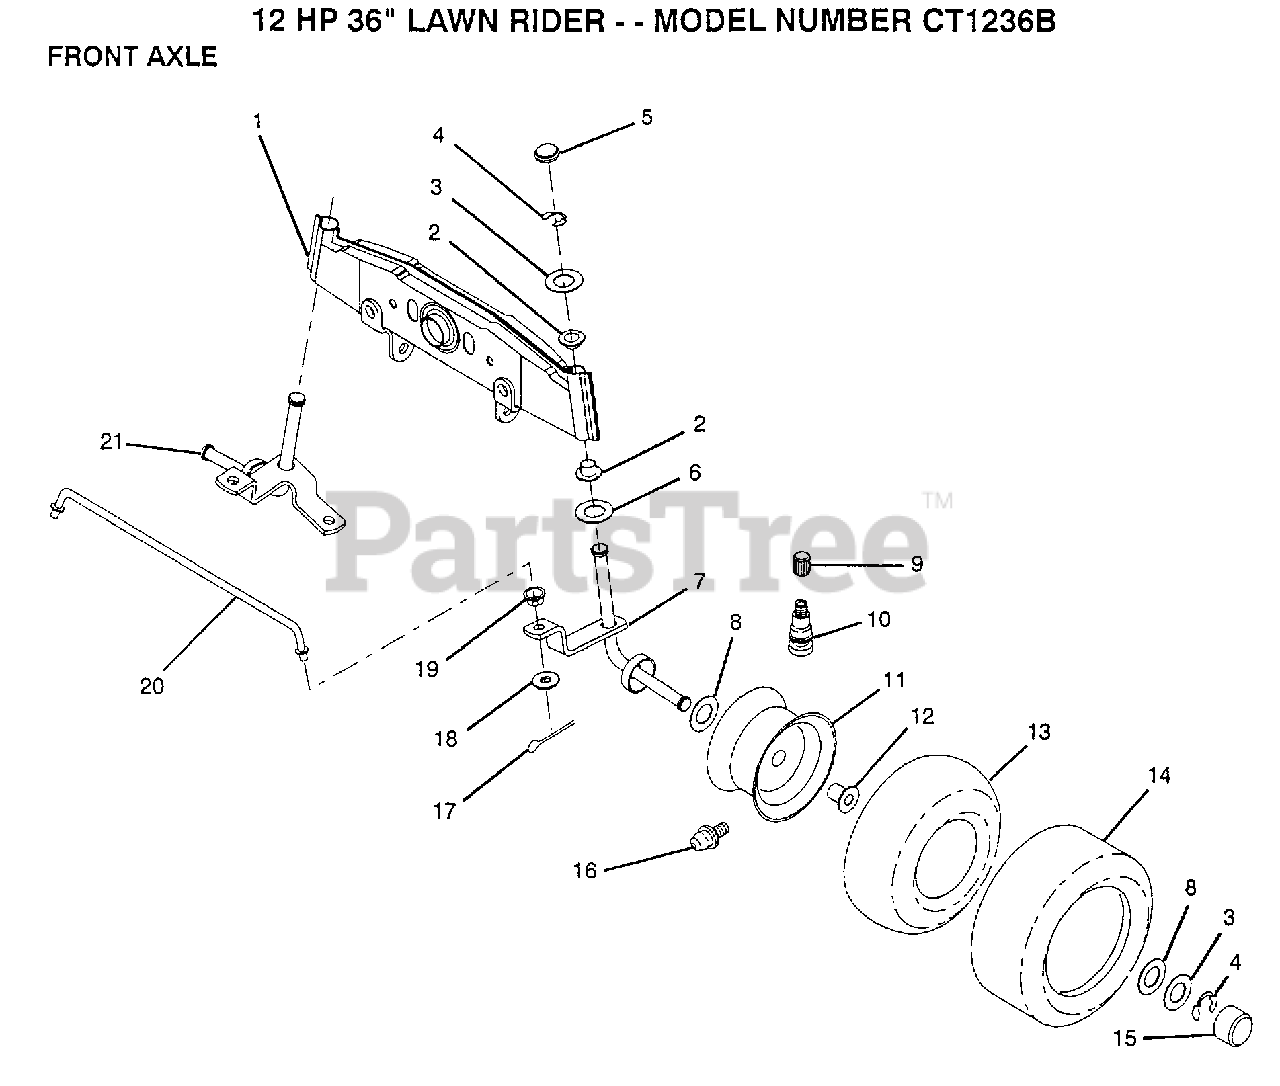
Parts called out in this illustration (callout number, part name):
2	NYLINER
3	WASHER
4	RING
5	CAP
6	WASHER .T
7	SPINDLE RH
8	WASHER
9	VALVE CAP
10	VALVE STEM LT
12	"FLANGE, BEARING"
13	TUBE.5.3/4.5/6
15	HUB CAP
16	FITTING LT
17	COTTER PIN
18	WASHER
19	BUSHING.DRAGLINK
20	ROD TIE
21	SPINDLE LH
